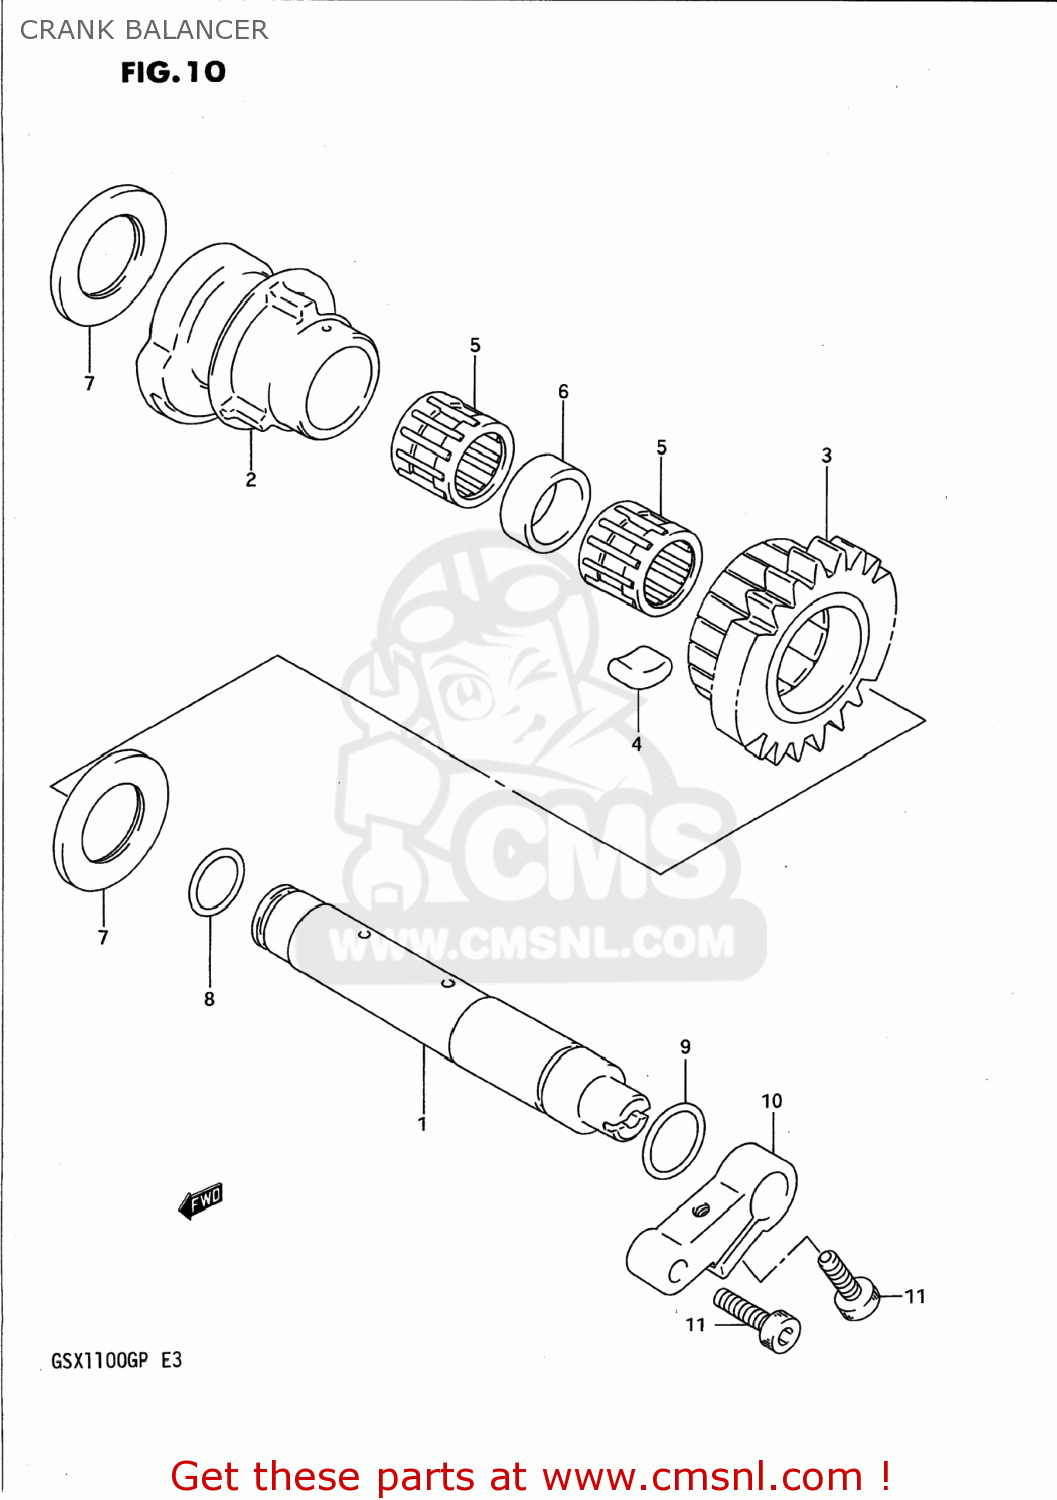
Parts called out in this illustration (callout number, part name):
1	SHAFT COMP,BALANCER
2	BALANCER,CRANKSHAFT
3	GEAR,CRANK BALANCER
4	DAMPER,BALANCER GEAR
5	BEARING 19X25X22.8
6	SPACER (19X25X10)
7	WASHER (22X40X1)
8	O RING(D:1.9,ID:14.5)
9	O RING(D:1.9,ID:16.6)
10	ARM,BALANCER SHAFT
11	BOLT
